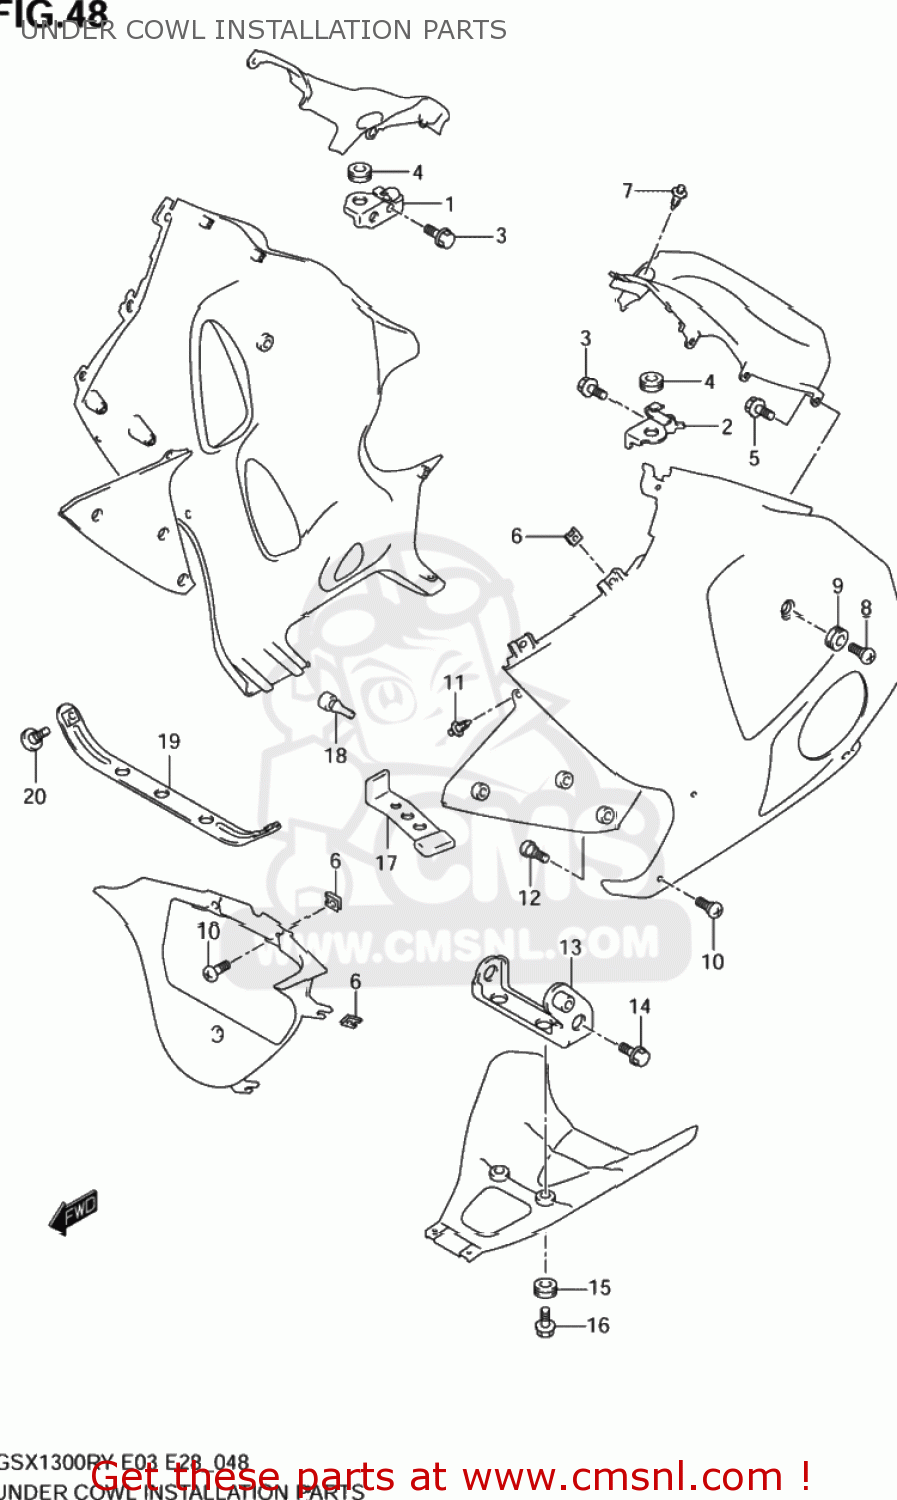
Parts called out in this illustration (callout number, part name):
1	BRACKET,PANEL,R
2	BRACKET,PANEL,L
3	BOLT
4	CUSHION
5	SCREW 5X8
6	NUT,COWL
7	CLIP
8	SCREW(6X20)
9	CUSHION
10	SCREW(5X16)
11	CLIP(BLACK)
12	SCREW
13	BRACKET,RR UNDER COWLING
14	BOLT
15	CUSHION
16	SCREW(6X20)
17	BRACKET,UNDER COWLING,L
18	CUSHION
19	PLATE,UNDER COWLING
20	SCREW(5X16)
